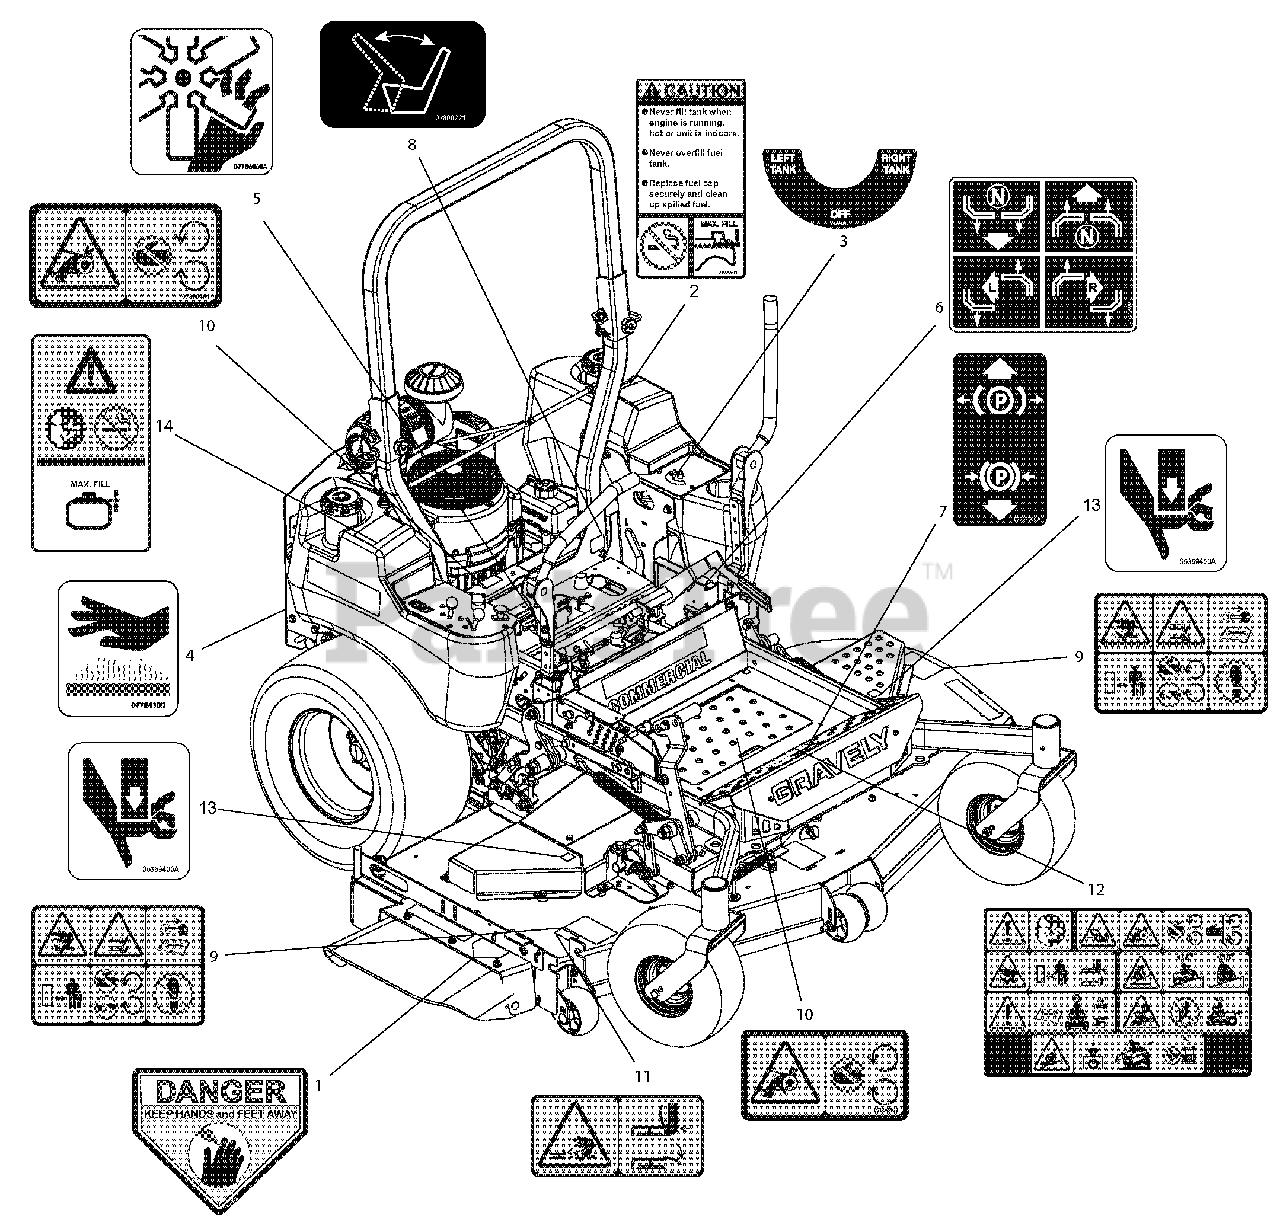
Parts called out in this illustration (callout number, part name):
1	DECAL, DANGER
2	DECAL, COM FUEL TANK FILL INST
3	DECAL, FUEL VALVE
4	DECAL HOT SURFACE
5	DECAL, DANGER - FAN
6	DECAL, PARKING BRAKE LEVER
7	DECAL, INSTRUCTIONAL - STEERING
8	DECAL, SEAT RELEASE
9	DECAL, SAFETY - MOWER DECK
10	DECAL, SAFETY - GUARDING
11	DECAL, SAFETY - DECK GUARDING
12	DECAL, MAIN SAFETY, COMMERCIAL
13	DECAL, PINCH POINT
14	DECAL, FUEL WARNING
